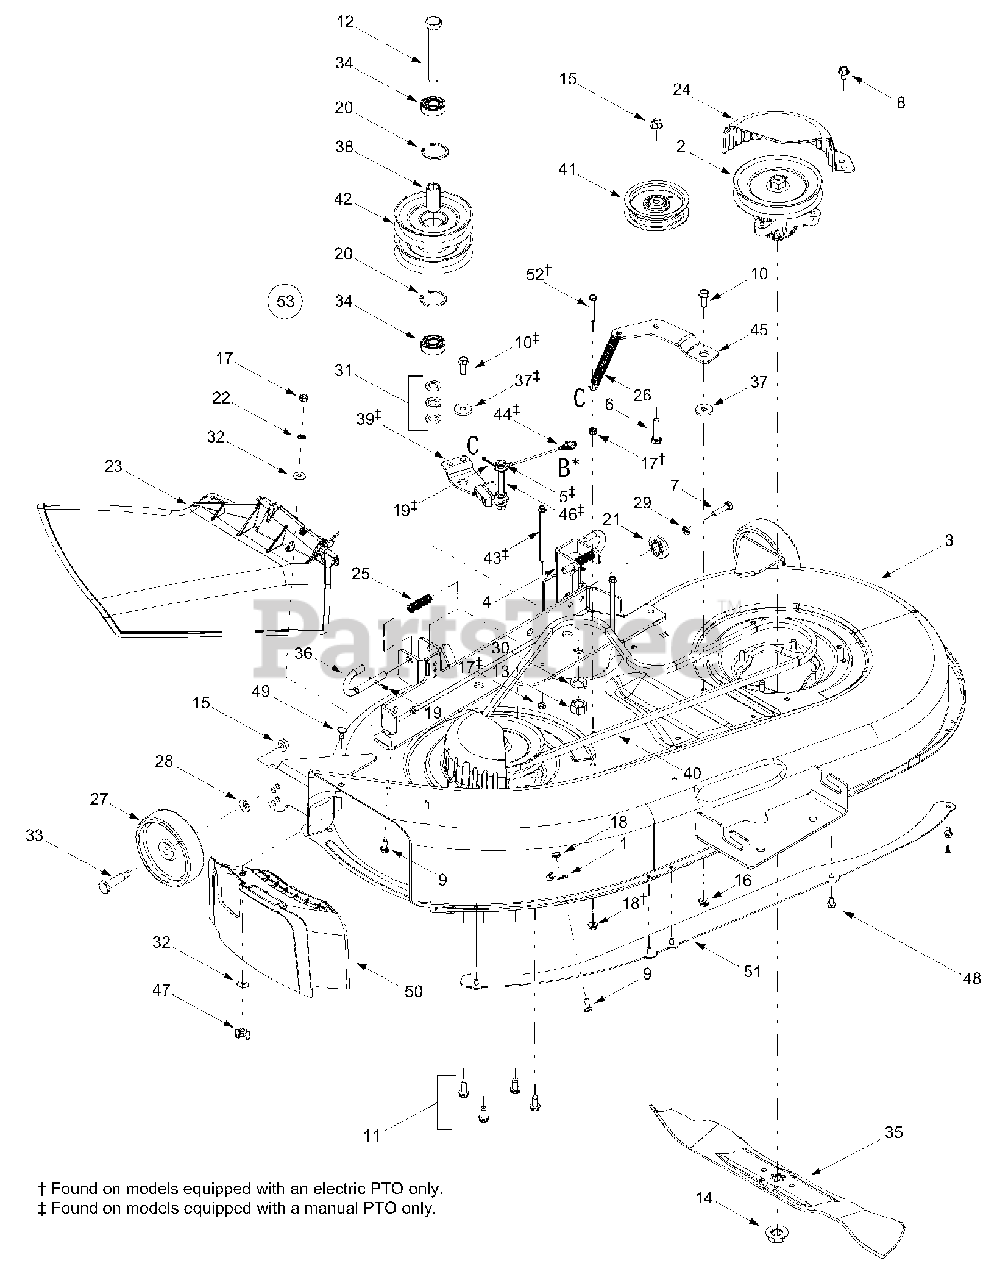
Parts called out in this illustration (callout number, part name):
1	Retainer Hook
2	Spindle Assembly, 5.75 Dia.
5	Flat Washer, .385 x .62 x .063
6	Hex Cap Screw, 1/4-20 x 1.5
7	Hex Cap Screw, 5/16-18 x 1.25
8	Self-tapping Screw, 5/16-18 x .625
9	Hex Cap Screw, 1/4-20 x .62
10	Hex Head Washer Screw, 5/16-18 x .875
11	Self-tapping Screw, 5/16-18 x .75
12	Hex Cap Screw, 5/8-18 x .875
13	Hex Nut, 5/8-18
14	Hex Flange Nut, 5/8-18
15	Flange Lock Nut, 3/8-16
16	Flange Lock Nut, 5/16-18
17	Hex Nut, 1/4-20
18	Hex Flange Lock Nut, 1/4-20
19	Cotter Pin, 1/8 x 1.25
20	Internal Snap Ring
21	Deck Adjustment Gear
22	Push Nut. .25 x .5
23	Side Discharge Chute Assembly
24	Belt Cover
25	Compression Spring, .406 x .531 x 1.75
26	Extension Spring, .50 x 4.74
27	Deck Wheel, 5 x 1.38
28	Bell Washer, .401 x .87 x .063
29	Lock Washer, 5/16
30	Lock Washer, 5/8
31	Flat Washer, .64 x 1.0 x .12
32	Bell Washer, .265 x .75 x .062
33	Shoulder Screw, .498 x 1.53
34	Bearing, .625 x 1.574 x .470
35	Three-in-one Blade, Star Center, 21.23"
36	Deck Release Pin
37	Shoulder Spacer, .625 x .324
38	Spacer, .635 x .88 x 1.72
39	Deck Brake Assembly
40	Deck Belt
41	Idler Pulley, 3.5
42	Double Pulley, 5.0
43	Self-tapping Screw, 1/4-20 x 4.0
44	Brake Cable, 5.05
46	Pin, 3/8-16, 3/8 x 3.27
47	Wing Nut, 1/4-20
48	Self-tapping Screw, 1/4-20 x .5
49	Carriage Screw, , 1/4-20 x .62
50	Mulch Plug
52	Hex Cap Screw, 1/4-20 x 1.75
